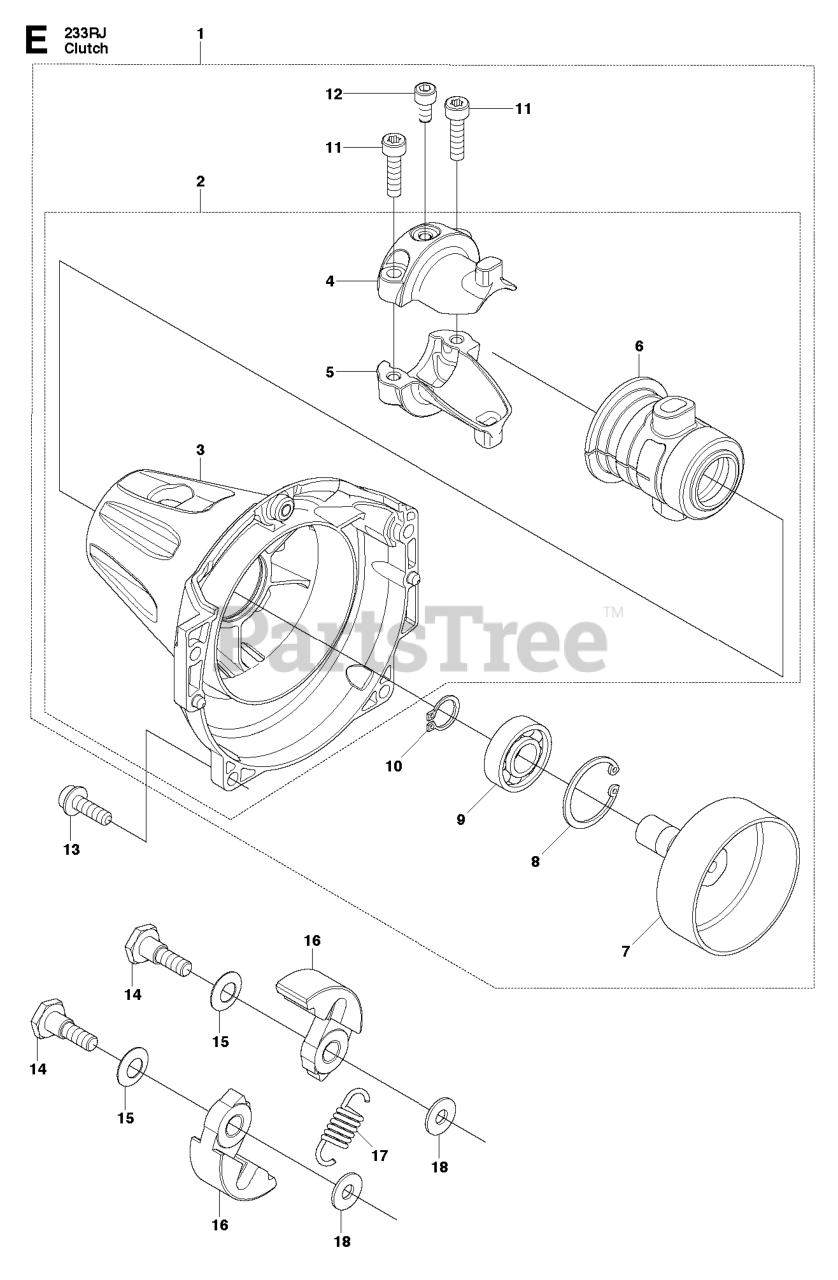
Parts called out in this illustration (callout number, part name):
2	HOUSING COMP.
4	BRACKET (A) (RPLS T170031211)
5	BRACKET (B)
6	CUSHION (RPLS T170031231)
7	DRUM (RPLS 481031120-22)
9	BEARING
11	RP BOLT TORX M5XL20 T27
12	BOLT TORX M5XL10 T27
13	BOLT
14	BOLT
15	WASHER (RPLS 1140-51241)
16	SHOE
17	SPRING
